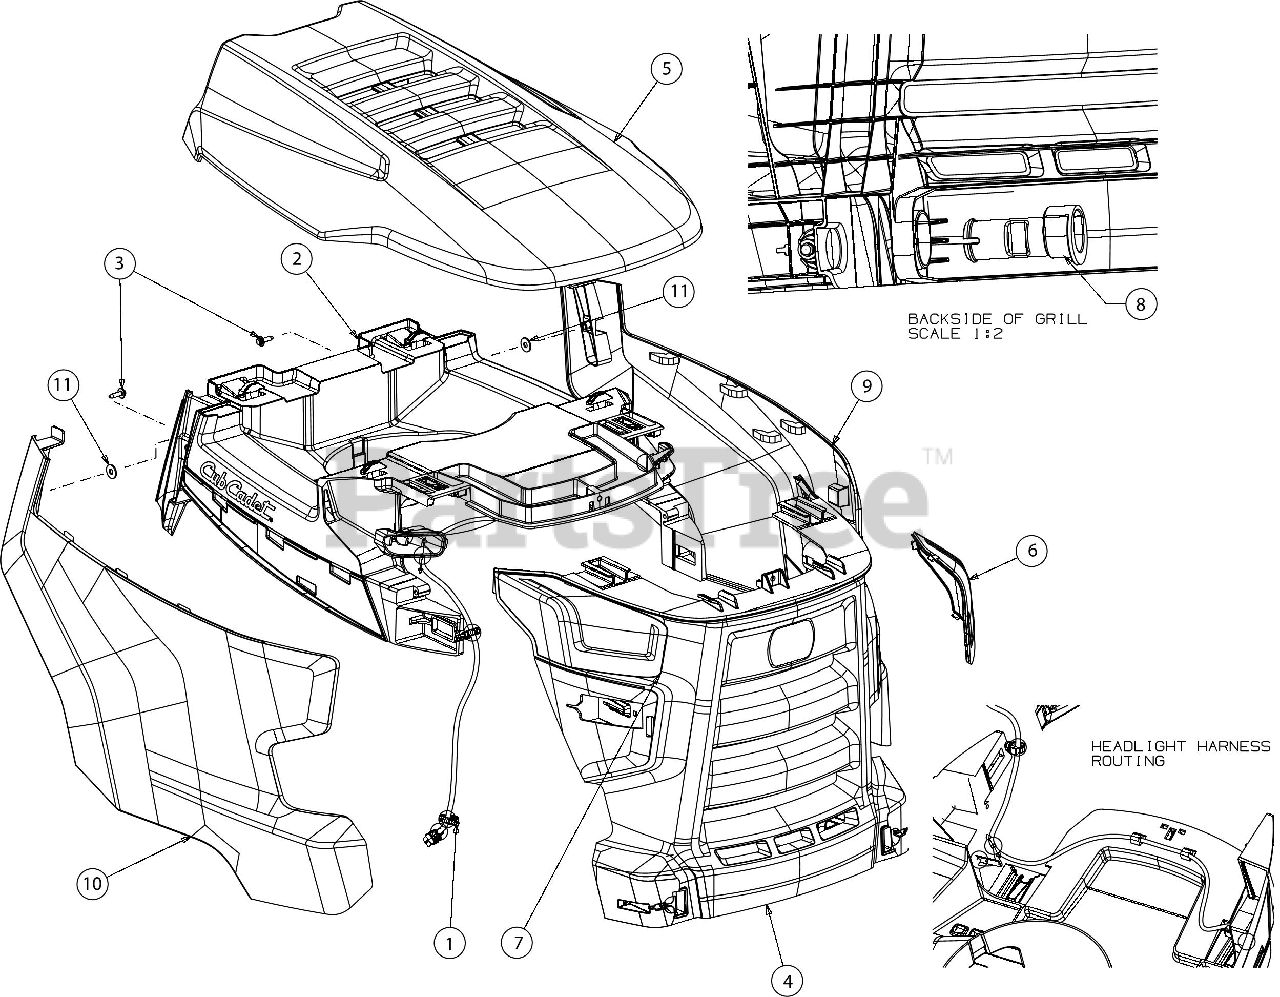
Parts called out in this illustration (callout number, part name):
1	HEADLIGHT HARNESS ASSEMBLY W/LED
2	PLENUM/HOOD FRAME
3	SCREW 1/4-10 x .750
5	HOOD TOP
6	HEADLIGHT LENS-LED
7	HEADLIGHT LENS-LED
8	HOOD PIVOT PIN
9	SIDE PANEL (LH)
10	SIDE PANEL (RH)
11	FLAT WASHER .28 ID x .74 OD x .063
